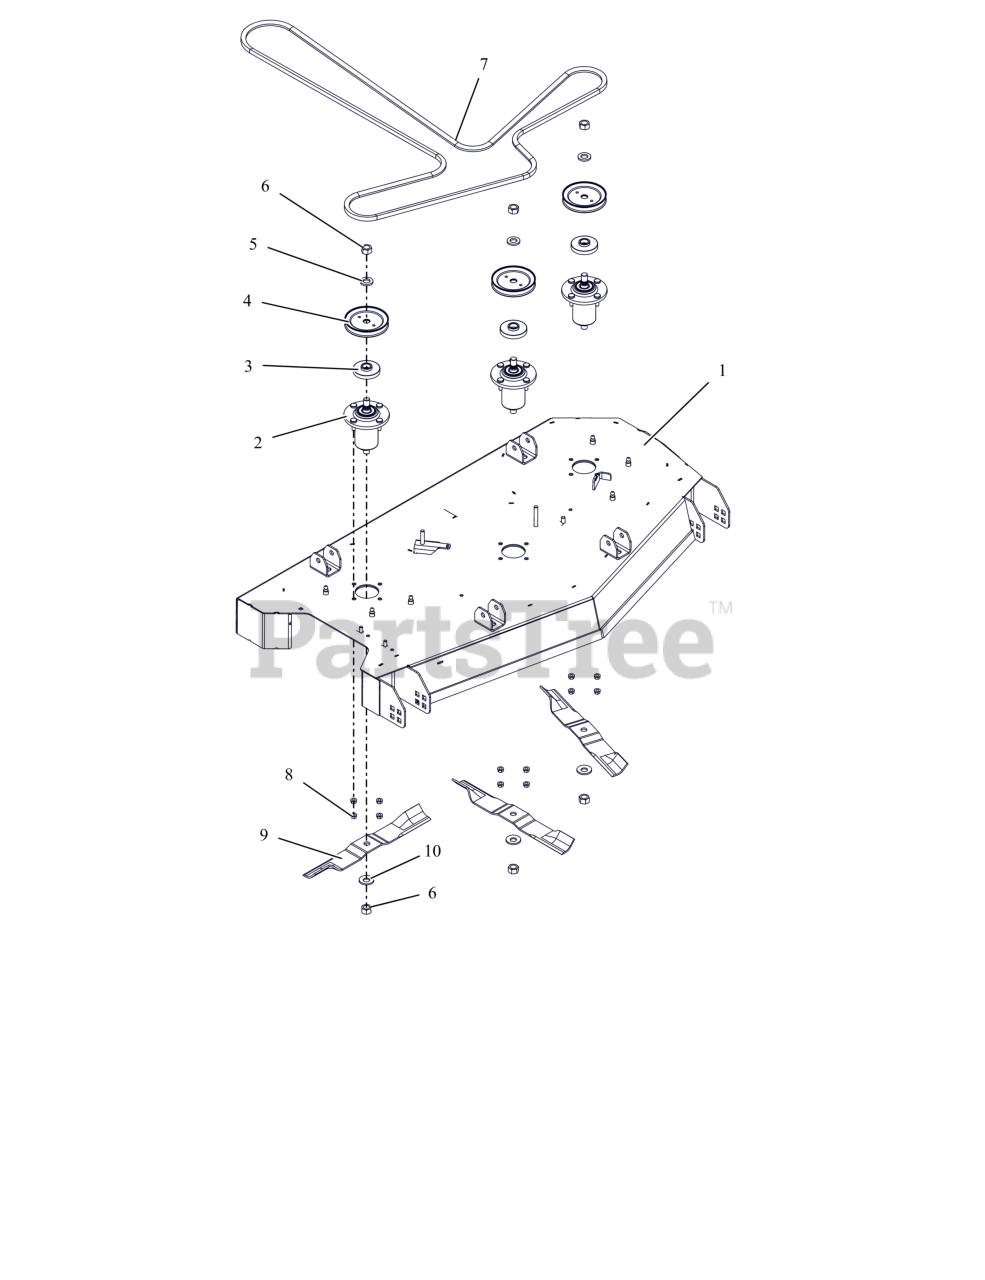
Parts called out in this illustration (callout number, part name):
1	KIT-GRAVELY DECK 48" W/ DECALS
2	ASM, ALUMINUM SPINDLE SUB
3	SHIELD, DUST
4	PULLEY-V-4.50 ODX.625SPLINE ID
5	SPCR- .735 X 1.313 X .165
6	NUT-STD .625-18 ZCC
8	NUT,LK-CTR-FLG .31-18 GF ZCC
9	BLADE- 16.5" MOWER (HI-LIFT)
10	WSHR-BLVL .669X1.535X.138
